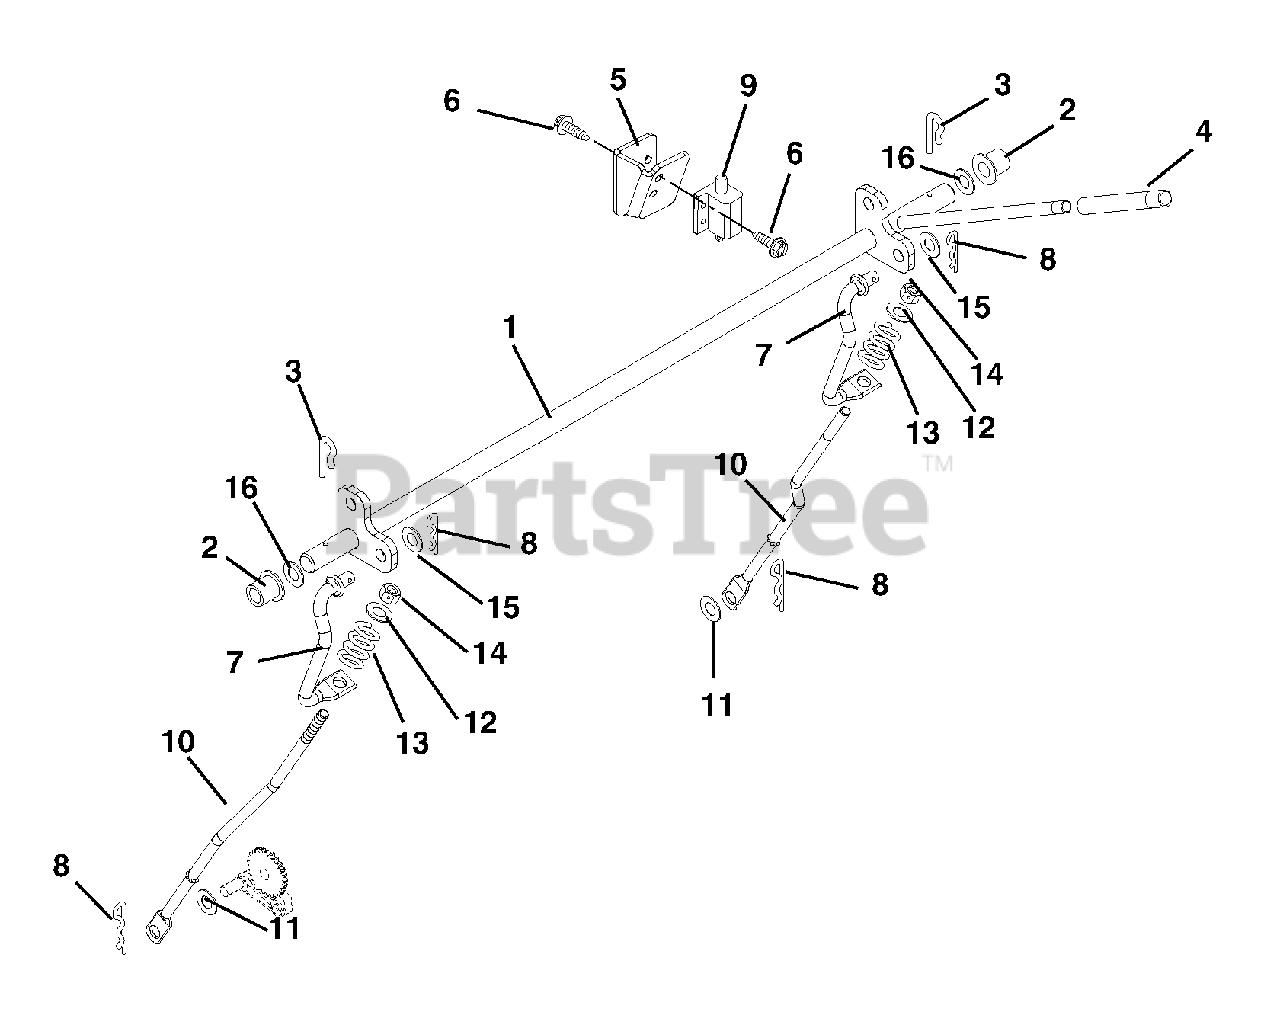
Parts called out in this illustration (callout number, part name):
1	Weldment, Parking Brake
2	Bushing, Flange .63 x 1.00 x .625 Nylon
3	Pin, Spring Clip
4	Grip, Hand Clutch Lever
5	Bracket, Brake Switch
6	Screw, Tapping 10-24 x .50 Hex Washer Head
7	Rod, Over Center
8	Pin, Hair
9	Switch, Interlock NC
10	Rod, Park Brake
11	Washer, Flat Steel .406 x 1.00 x .188
12	Washer, Flat Steel .344 x .688 x .065
13	Spring, Compression .063 x .53 x 1.187
14	Nut, Locking Nylon .312-18
15	Washer, Flat Steel .406 x .812 x .065
16	Washer, Flat Steel .627 x .99 x .032
